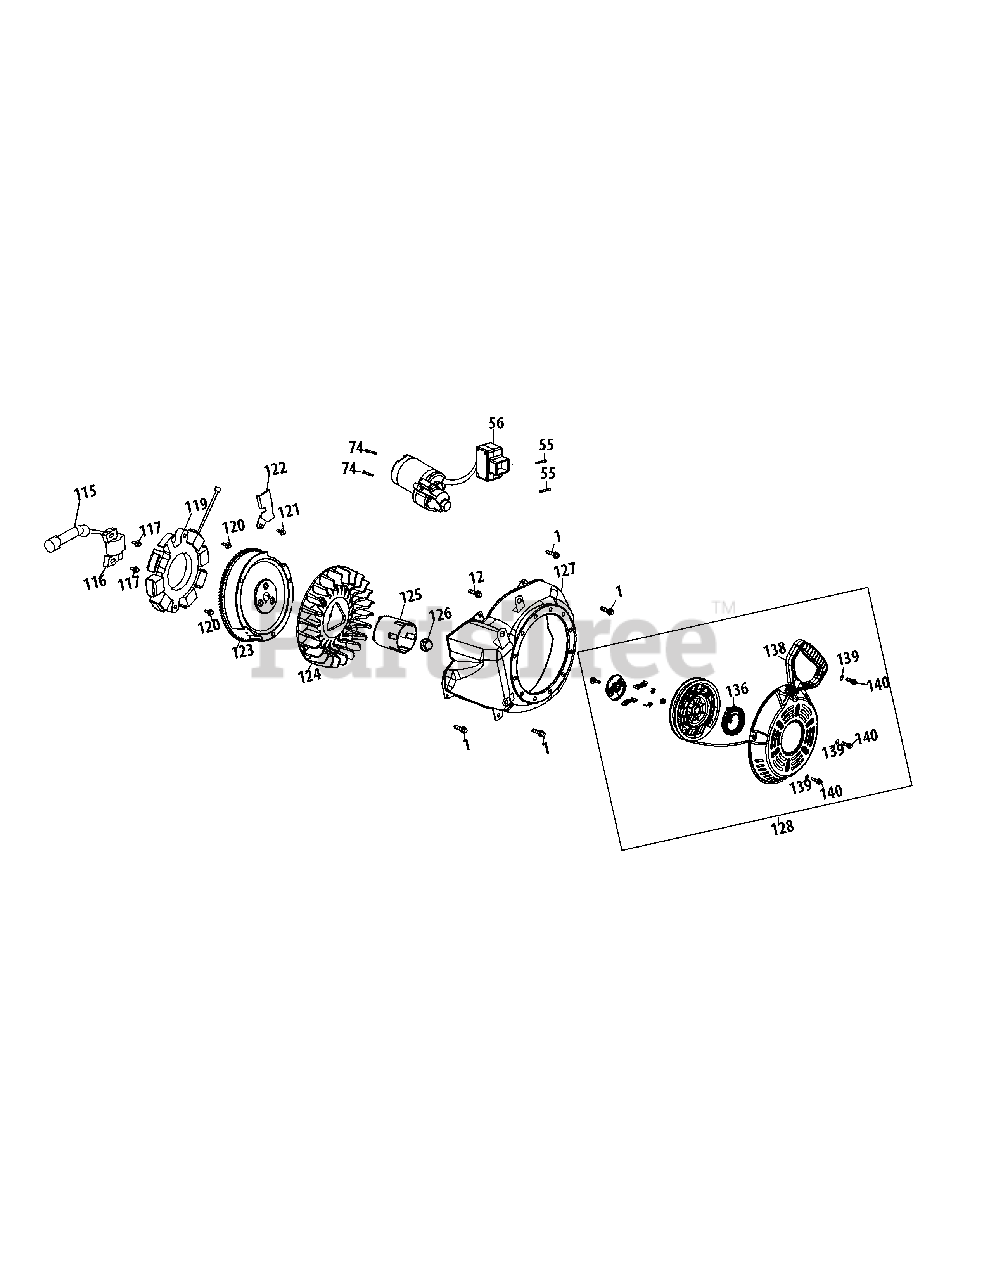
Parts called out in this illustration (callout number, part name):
1	BOLT M6×12
12	BOLT M6×16
55	BOLT M4×55
56	ELECTRIC STARTER
74	BOLT M8×55
116	IGNITION COIL ASSEMBLY
117	IGNITION COIL BOLT
119	ALTERNATOR ASSEMBLY
120	BOLT M6×30
121	BOLT M6×8
122	WIRE PLATE
124	COOLING FAN
125	STARTER CUP
126	NUT, SPECIAL, M16×1.5
127	BLOWER HOUSING
128	RECOIL STARTER
136	RECOIL SPRING
138	STARTER HANDLE
139	GASKET 06
140	BOLT M6×10
